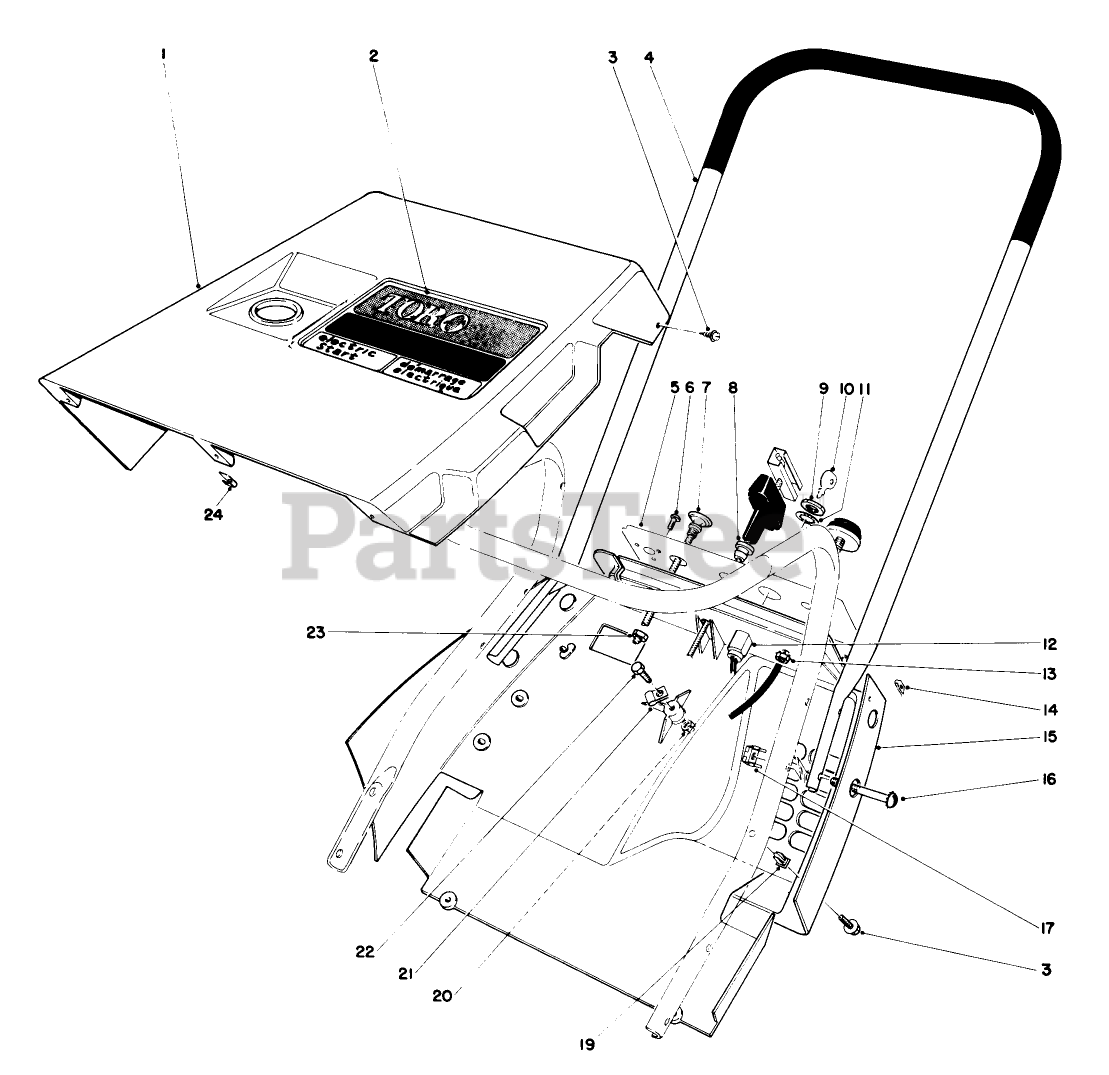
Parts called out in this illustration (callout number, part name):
3	SCREW-HWHTF
6	SCREW-PLASTITE
8	GUIDE-ROPE, STARTER
9	NUT-HH
11	WASHER-LOCK
12	SWITCH-ON / OFF
13	NUT-KEPS
14	NUT-TYPE J
17	TINNERMAN NUT
20	NUT-LOCK, NI
22	SCREW-SHWH
